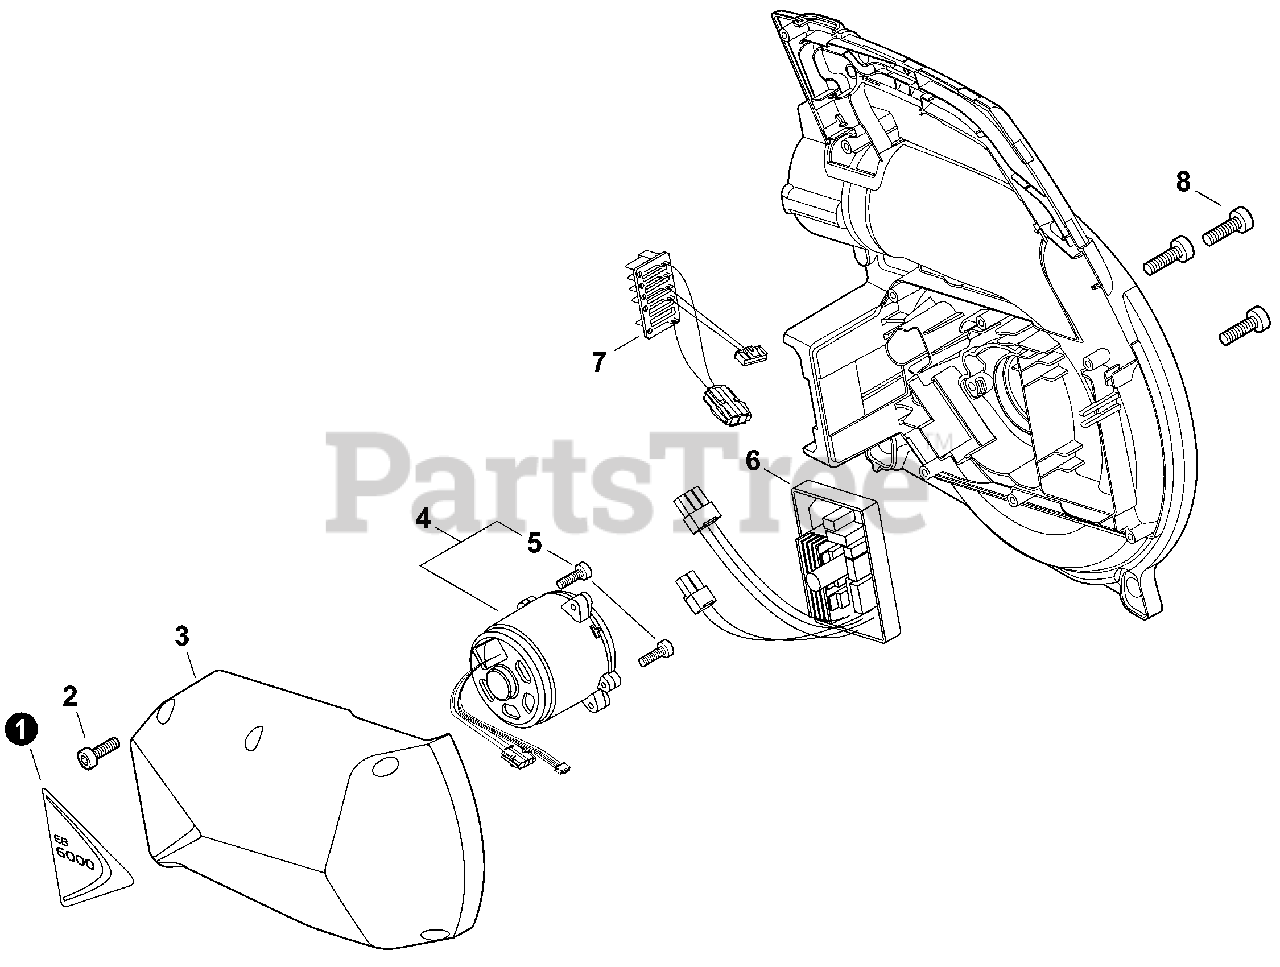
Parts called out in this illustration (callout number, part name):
1	LABEL, MODEL EB6000
2	BOLT, TORX 4×16
3	COVER, MOTOR
4	MOTOR ASSY
5	BOLT, TORX 4×12
6	CONTROL BOARD ASSY
7	TERMINAL, LEAD
8	BOLT, TORX 5×20
